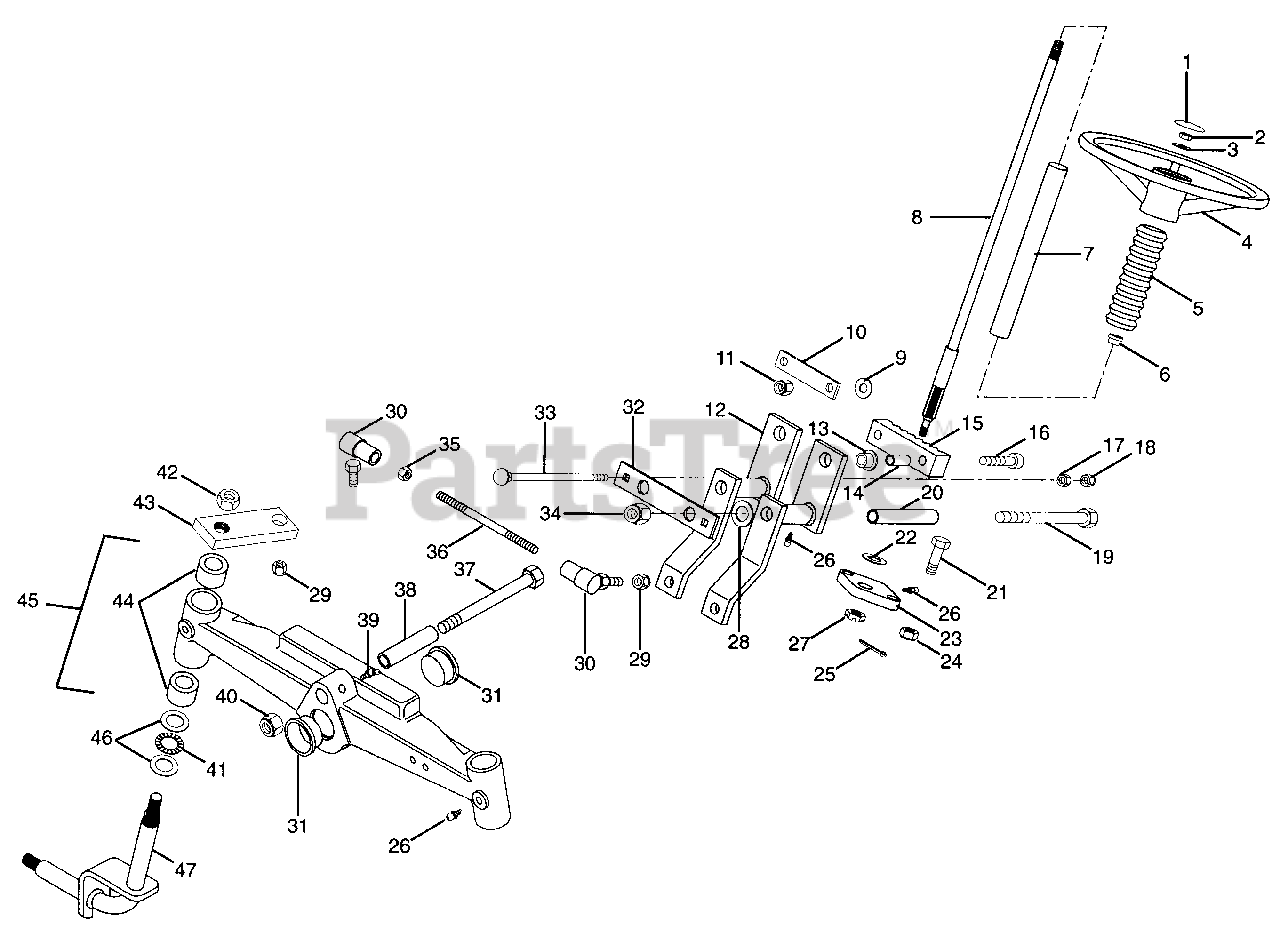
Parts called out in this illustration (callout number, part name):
1	Steering Wheel Cap
2	Nut-Jam .625-11
3	Washer-Flat-Steel .656 x 1.312 x .095
4	Steering Wheel
5	Steering Column Boot
6	Bushing-Flange .762 x 1.0 x .580 x 1.48
7	Tube-Plastic 1.0 I.D.
8	Weldment-Steering Shaft
9	Washer-Flat-Steel .38 x .875 x .083
10	Strap-Rack and Pinion
11	Nut-Locking-Center .375-16 Grade 2
12	Weldment-Steering
13	Bushing-Flange .627 x .879 x .469 x 1.120
14	Bushing-Steel .391 x .621 x .676
15	Grade-Rack
16	Bolt-Hex .38-16 x 2.00
17	Nut-Hex .312-18 Grade 2
18	Nut-Locking-Center .312-18 Grade 2
19	Bolt-Hex .50-13 x 6.00
20	Sleeve-Pivot
21	Bolt-Hex .44-14 x 1.50
22	Washer-Thrust .507 x .917 x .031
23	Support-Steering Shaft
24	Nut-Locking-Center .44-14
25	Pin-Cotter .09 x 1.00
26	Fitting-Lube .25-28 x .256
27	Nut-Hex-Slotted .500-13
28	Bearing-N-Thrust .752 x 1.24 x .093
29	Nut-Locking-Nylon .375-24 Grade 2
30	Joint-Steering Ball
31	Cap-Front Axle
32	Plate-Adjustment
33	Bolt-Round Head Square Neck .31-18 x 5.50 Grade 2
34	Nut-Locking-Center .50-13 Grade 5
35	Nut-Jam .375-24 Grade 2
36	Rod-Steering
37	Bolt-Hex .75-10 x 4.50
38	Tube-Axle Pivot
39	Fitting-Lube 45 Deg
40	Nut-Locking-Center .75-10 Grade 2
41	Bearing-Thrust .875 x 1.427 x .078
42	Nut-Hex .625-11 Grade 2
43	Arm-Tie Rod Axle
44	Bushing-Sleeve .866 x 1.004 x 1.000
45	Axle-Steering
46	Washer-Thrust .877 x 1.427 x .032
47	Weldment-King Pin
